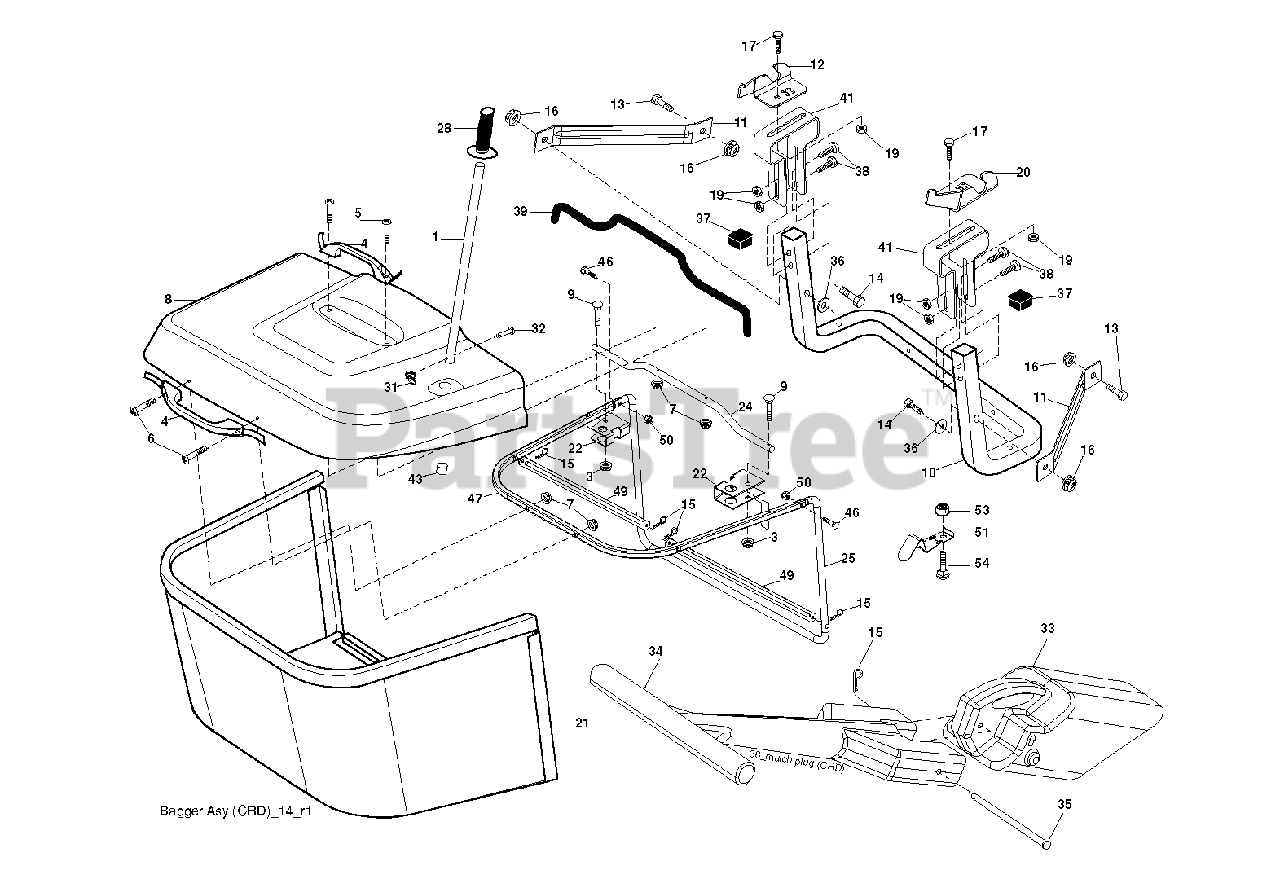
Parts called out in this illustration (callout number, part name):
1	TUBE HANDLE
3	NUT T
5	SCREW.PAN.HEAD
11	BRACKET
14	BOLT-HEX EAK
15	RETAINER-SPRNG RB
16	NUT LOCK FLG 3/8-16 UNC
17	BOLT
19	NUT LOCK HEX FLANGE 5/16-18
20	BRKT.PIVOT.RH.CRD
21	BAGGER.ASM.CRD.2007
22	BRACKET
24	TUBE
28	GRIP.HANDLE.BLACK
31	RETAINER CLIP
32	RIVET,DRILLED
33	PLUG
35	PIN
38	BOLT.5/16-18X2.5
39	SEAL.BAGGER.CRD
41	BRKT, BAGGER
43	PLUG, TUBING END
46	BOLT.CARRIAGE.5/16-18
50	NUT.71038.31-18.HEX.NYLOCK
53	NUT
54	BOLT
